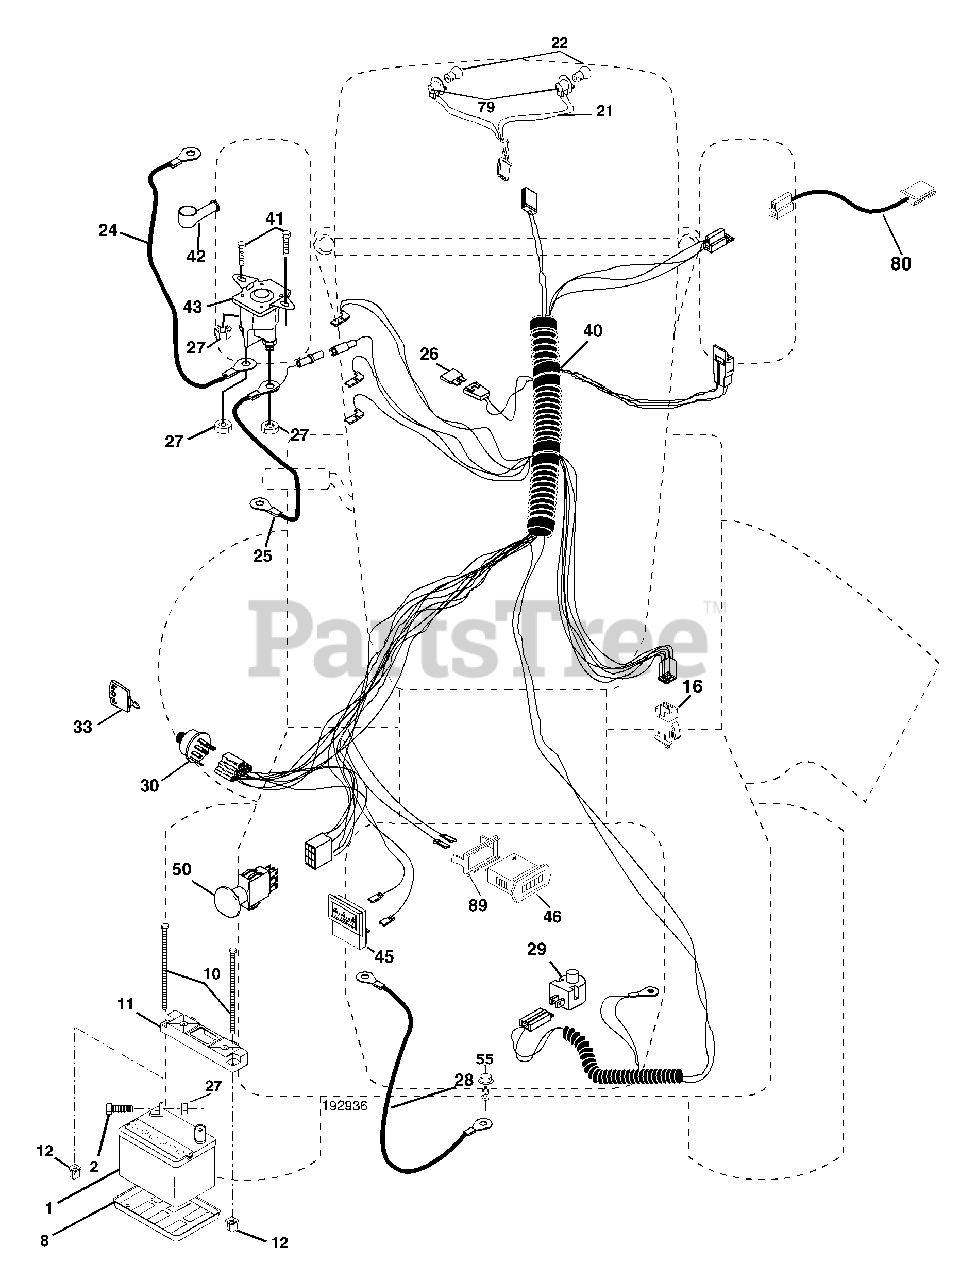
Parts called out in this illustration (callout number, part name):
1	Battery
2	Bolt, Hex 1/4-20 x 3/4
8	Tray, Battery
10	Bolt, Btr Front 1/4-20 x 7-1/2
11	Holddown Battery Front Mount
12	Nut, Push Nylon Battery Front 1/4
16	Switch Interlock
21	Harness, Light
22	Light Bulb
24	Cable, Starter
25	Cable, Battery
26	Fuse
27	Nut Keps Hex 1/4-20 unc
28	Cable, Ground
29	Switch, Seat
30	Switch, Ignition
33	Key, Molded
40	Harness, Ignition
41	Screw Thd Cut 1/4-20 x 1/2
42	Cover, Terminal
43	Solenoid
45	Ammeter
46	Hourmeter
50	Switch, PTO
55	Screw Thdrol 5/16-18 x 1/2
79	Socket Asm bulb Twistlock
80	Harness Clutch EVX
89	Bracket Snap-In
